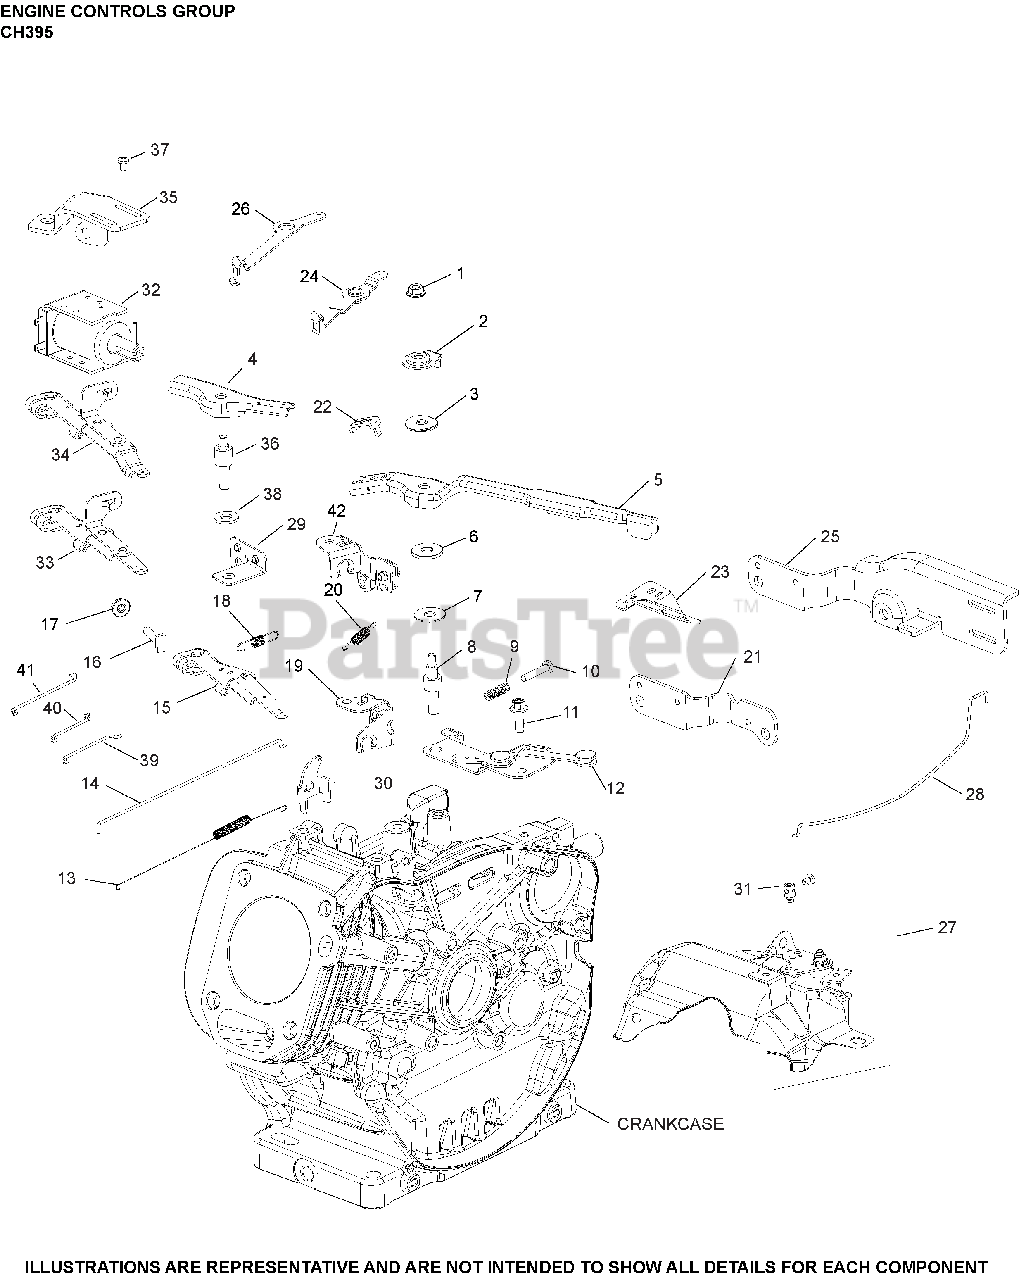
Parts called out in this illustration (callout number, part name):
1	NUT, HEX FLANGE LOCK (M6)
2	WASHER, CONTROL LEVER
3	WASHER, SPRING
5	CONTROL LEVER ASSEMBLY
6	WASHER, NYLON CONTROL LEVER
7	WASHER, FLAT
8	STUD, CONTROL LEVER
9	SPRING, COMPRESSION
10	SCREW, SPEED ADJUSTING
11	SCREW, M6 X18
12	BRACKET, CONTROLS ASSY
13	SPRING, LINKAGE
14	LINKAGE, GOVERNOR
15	KIT, GOVERNOR LEVER
16	SCREW, RECTANGLE HEAD (M6)
17	NUT, HEX FLANGE (M6) - USE 14 100 16-S
18	SPRING, GOVERNOR
20	SPRING, THROTTLE RETURN
22	CLAMP, CABLE
23	BRACKET, BOWDEN CABLE ASSY
